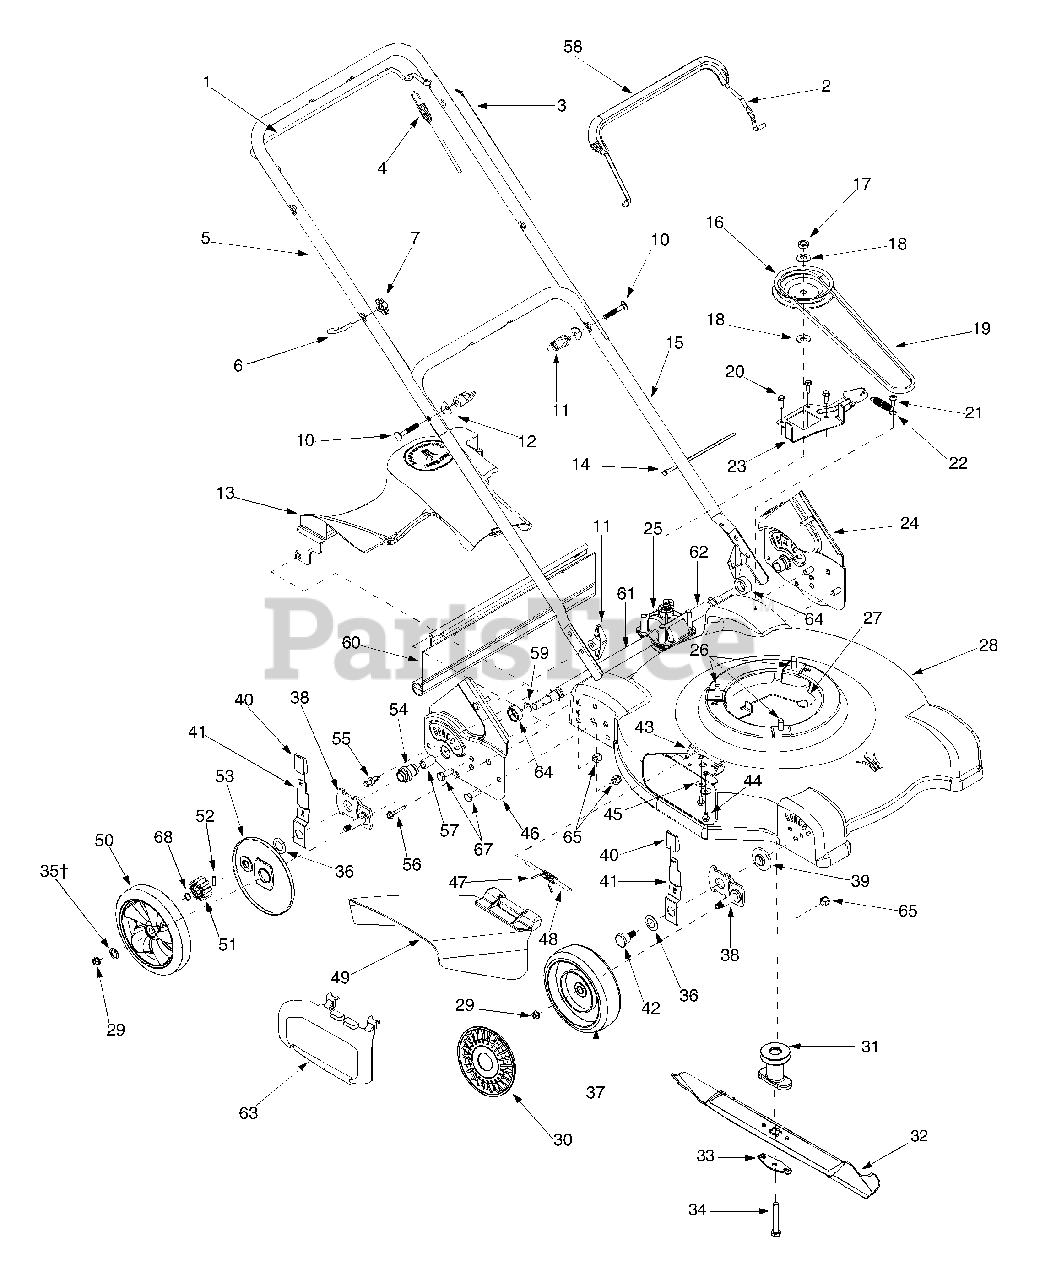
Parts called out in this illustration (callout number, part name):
1	Drive Control Handle
3	Blade Control Cable - 50.56"
4	Drive Control Cable
7	Wing Nut 1/4-20
10	Carriage Bolt 5/16-18 x 2.0
11	Wing Nut 5/16-18
12	Shoulder Washer.320 ID x.93 OD
13	Transmission Cover
16	Transmission Pulley
17	Jam Nut 7/16-20
18	Bell Washer.45 ID x 1.00 OD
19	V-Belt
20	Hex Washer Screw 1/4-20 x.75
21	Shoulder Screw.375 x.25
22	Extension Spring
23	Transmission Belt Bracket
26	Hex Washer Screw 3/8-16 x 1.0
27	Engine Belt Keeper Bracket
30	Hub Cap
31	One Piece Blade Adapter
32	22" Mulching Blade
33	Bell Blade Support
34	Hex Cap Screw 3/8-24 x 2.5
35	Flat Washer 1/2 x 1.00 x.030
36	Bell Washer.401 ID x.870 OD
37	Front Wheel
38	Pivot Arm Assembly
39	Height Adjuster Bearing
40	Height Knob
41	Spring Lever
42	Shoulder Screw 3/8-16
43	Deflector Chute Adapter
44	Hex Washer Screw 1/4-20 x.50
45	Bell Washer.265 ID x.75 OD
48	Hinge Pin
49	Side Discharge Chute Assembly
50	Rear Wheel
51	Spur Gear 14T RH
52	Pin
54	Bearing Support
55	Plastic Rivet
56	Screw 1/4-20
57	Sleeve Bearing
58	Snap-On Bail Cover
59	Retainer Ring
61	Sleeve Spacer.550 ID x 9.0 OD
62	Sleeve Spacer.550 ID x 2.44 OD
63	Snap Mulching Plug
64	Bearing Spacer
65	Hex Lock Nut 3/8-16
66	Hex Cap Screw 3/8-16 x 1.0
67	Snap Ring.500
